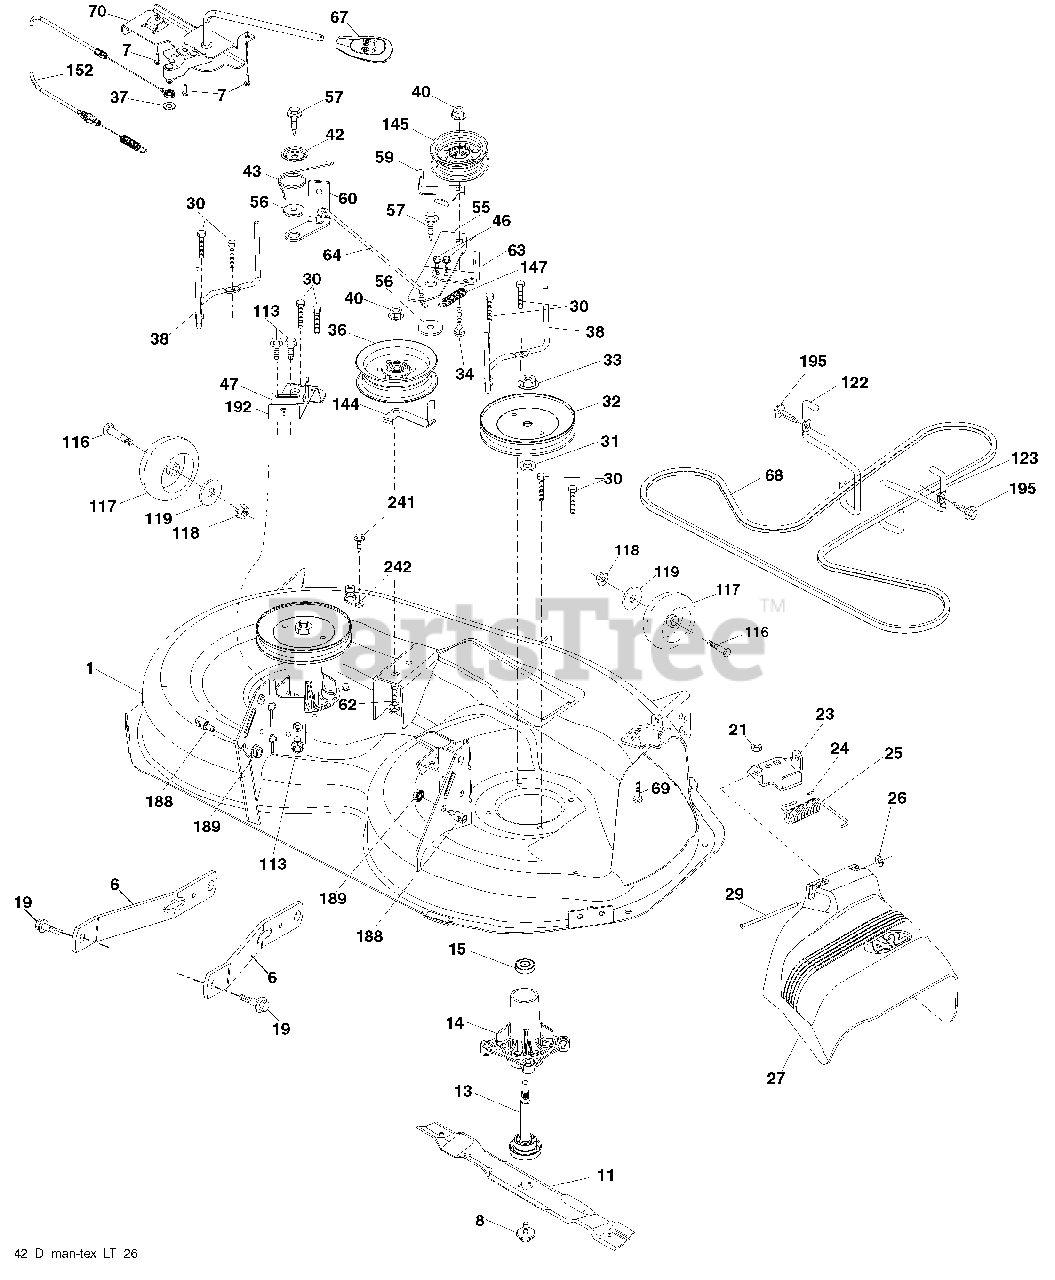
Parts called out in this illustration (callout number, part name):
1	Mower Housing
6	Arm Suspension
7	Screw #10 x 0.750 BOS Thread
8	Bolt/Washer Asm 7/16-20 unf
8	Blade, 42" Mulching Premium
11	Blade, 42" Hi-Lift
11	Blade, 42" Mulching Std
13	Shaft Assembly, Mandrel
14	Housing, Mandrel
15	Bearing, Ball, Mandrel
19	Bolt, Shoulder
21	Nut, Crownlock 5/16-18 unc
23	Bracket, Deflector
24	Cap, Sleeve
25	Spring, Torsion, Deflector
26	Nut, Push
27	Shield, Deflector
29	Rod, Hinge
30	Screw Thdrol Rolling Wsh Hd
31	Washer, Spacer
32	Pulley, Mandrel
33	Nut, Toplock, Flanged
34	Bolt Carr Sh. 3/8-16 x 1-1/2 Gr. 5
36	Pulley, Idler 4.50 RAW
37	Washer 13/32 x 13/16 x 16 Ga.
38	Keeper Belt LH Mandrel
40	Nut, Lock Flg. 3/8-16 unc
42	Spring Torsion Retainer
43	Spring Torsion Brake
46	Screw Thd Roll 1/4-20 x 5/8
47	Bracket Clutch Cable
55	Arm, Idler
56	Spacer, Retainer
57	Screw Hexwsh Thd 3/8-16 x 1
59	Guard, Tuv Idler (94)
60	Arm Brake Mower
62	Bolt Rdhd Sqnk 3/8-16 unc x 2
63	Arm Brake Mower
64	Linkage Brake
67	Handle, Clutch Cable
68	V-Belt
69	Bolt Rdhd Sqnk 5/16-18 x 5/8
70	Clutch Asm. Manual
113	Screw 5/16-18
116	Bolt
117	Wheel Gauge
118	Nut Lock 3/8-16 unc
119	Washer 3/8-7/8 x 14 Ga.
122	Keeper Belt Eng. LH
123	Keeper Belt Eng. RH
144	Keeper Belt
145	Pulley Idler Primary
147	Spring Return
152	Cable Clutch Manual w/Spr.
188	Stud Fastener
189	Nut Lock Hex Flange
192	Bracket Brake Stand LH
195	Screw Hexwsh Thdr 3/8-16 x 3/4
241	Vis
242	Port, Washout
242	Mandrel Assembly
242	Replacement Mower, Complete
